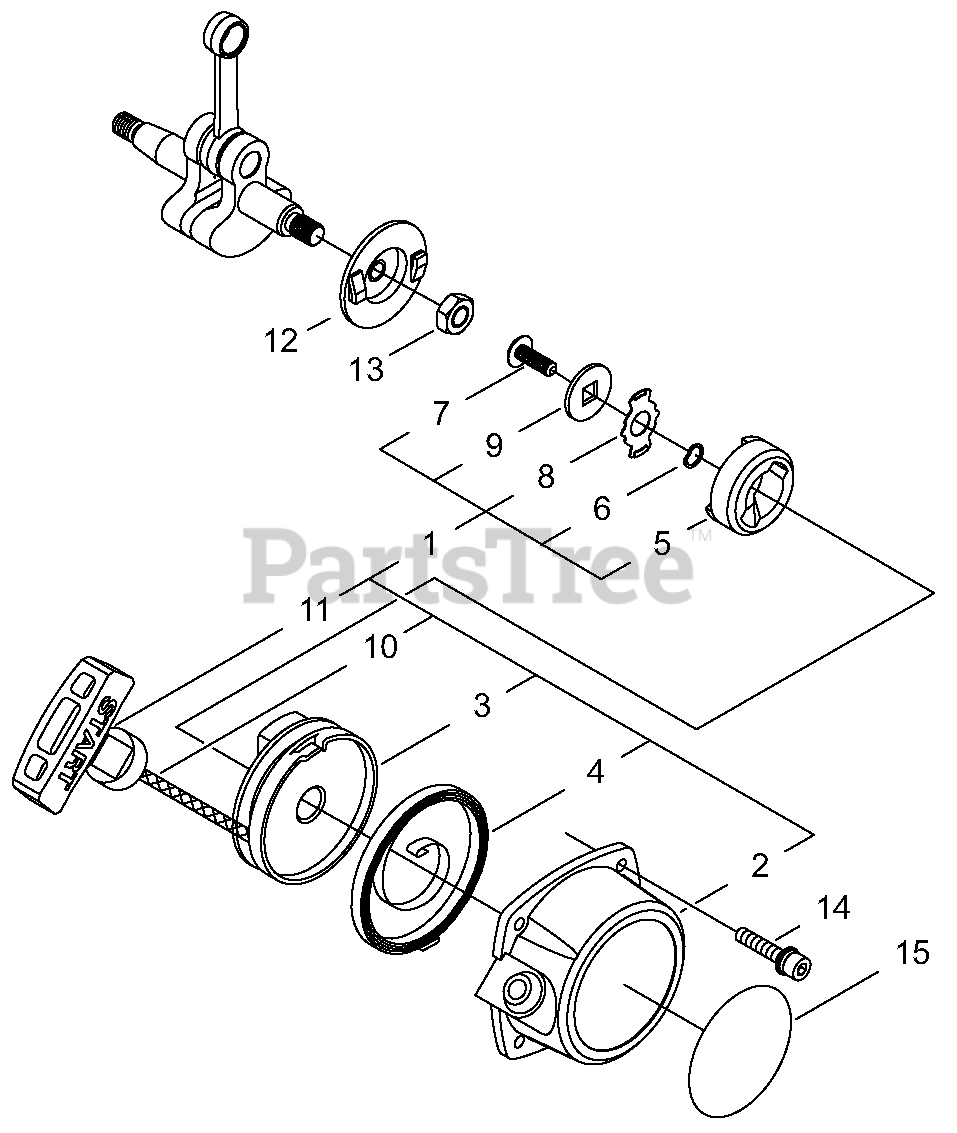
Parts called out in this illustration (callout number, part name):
1	STARTER ASSY
2	CASE, STARTER
3	REEL, ROPE
4	SPRING, REWIND
5	CATCHER, PAWL
6	WASHER - SPRING
7	SCREW - 5
8	RETAINER
9	WASHER - 5
10	ROPE, STARTER
11	GRIP, STARTER
12	PAWL, STARTER
13	NUT - 8
14	SCREW - 4X12
15	LABEL - TRADE
